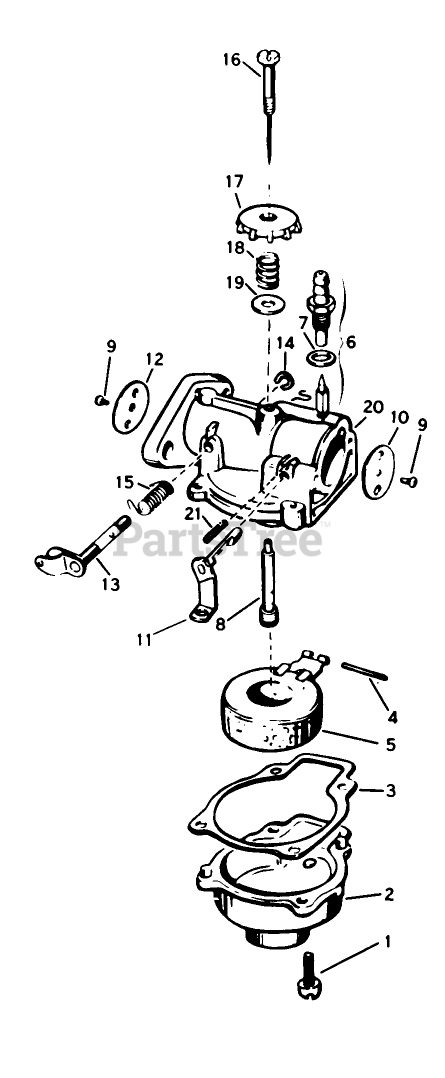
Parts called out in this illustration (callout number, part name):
1	Screw-Float Bowl to Carb.
9	Screw-Choke Disc
15	SPRING
16	NEEDLE AY. S
18	Spring-Ndl. Adj.
21	Spring-Choke Lever
